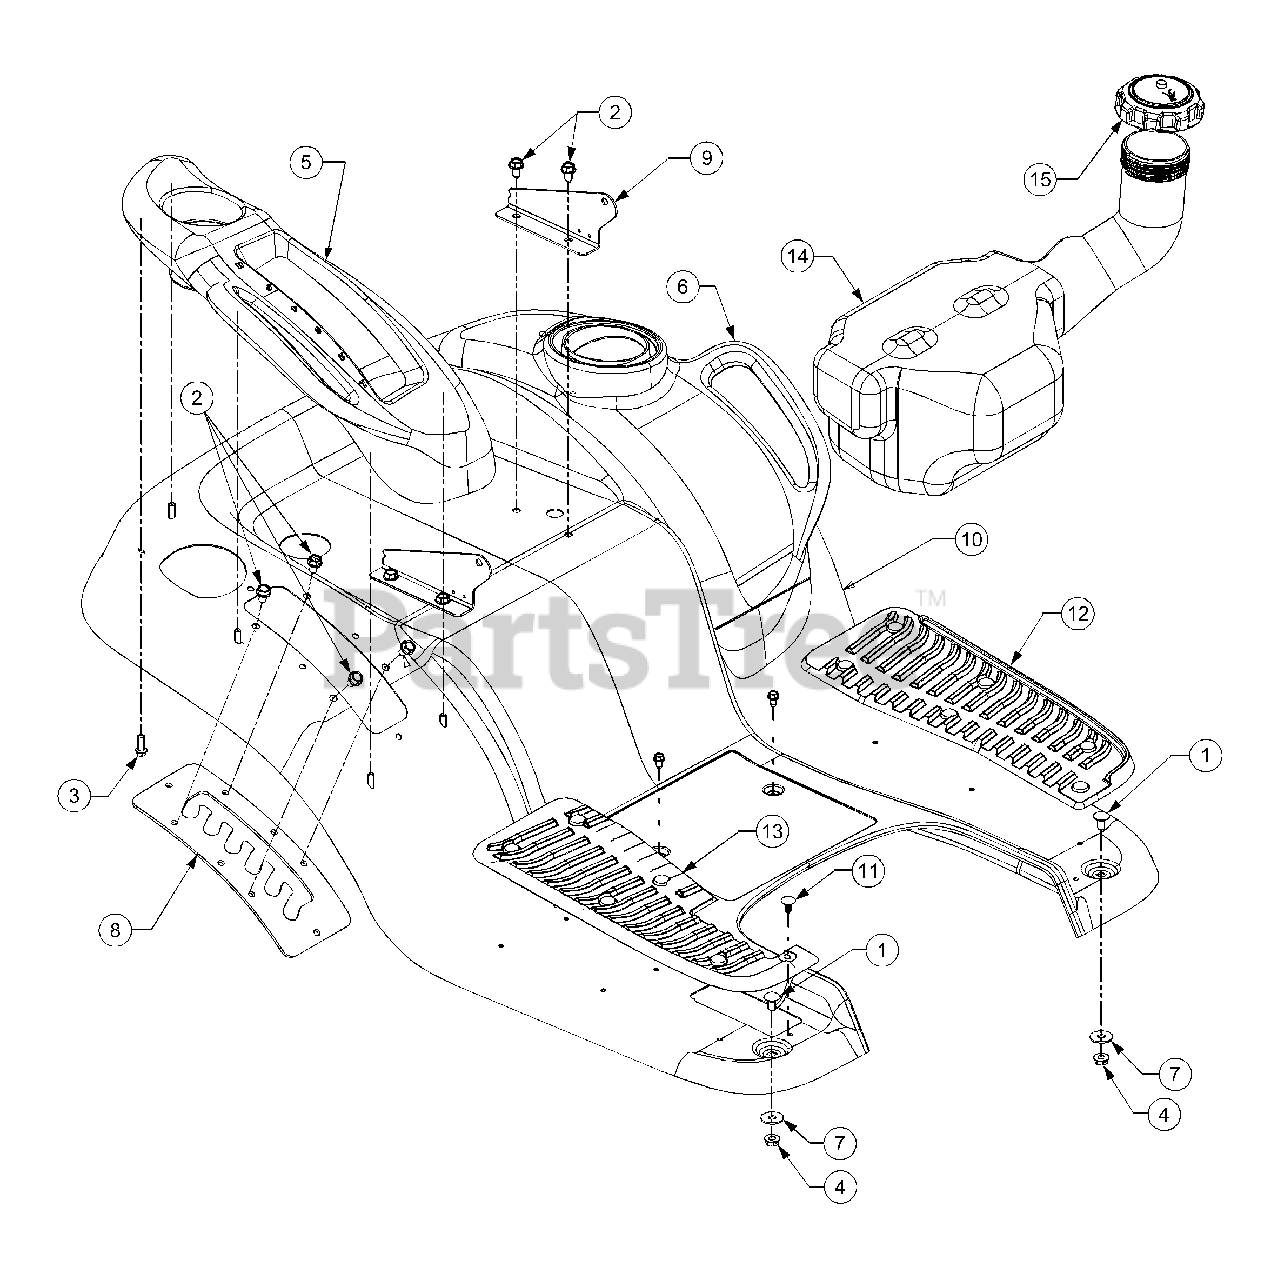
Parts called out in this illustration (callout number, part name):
1	Bolt, Carriage, 5/16-18 x .62 Lg
2	Screw, 5/16-12, 0.75
3	Screw, 1/4-15, 0.750
4	Nut, Nylon Lock, 5/16-18
5	Cover, Fender, RH
6	Cover, Fender, LH
7	Washer, Flat, .349 x 1.00 x .063
12	Pad, Foot, LH
13	Pad, Foot, RH
14	Tank, Fuel
15	Cap, Fuel
16	Screw, Self-tapping, 1/4-20, 0.500
